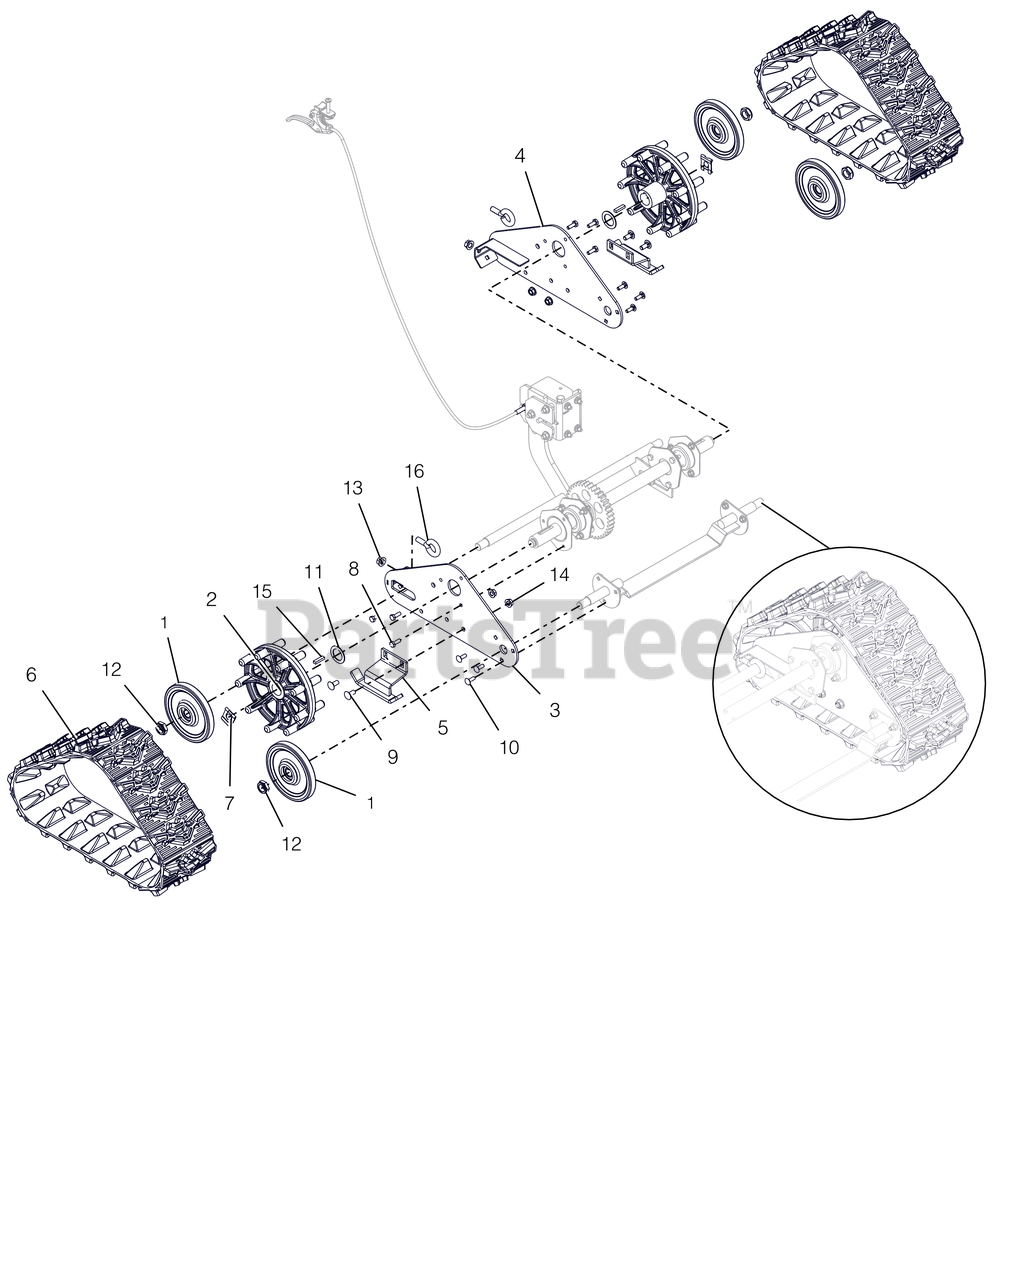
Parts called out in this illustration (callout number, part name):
1	WHEEL, BOGIE - SINGLE BEARING
2	WHEEL, MACHINED DRIVE
3	PLATE, SIDE-COMPACT RH WLDMT
4	PLATE, SIDE-COMPACT LH WLDMT
5	RUNNER, GUIDE-CMPT TRACK BLACK
6	TRACK, RUBBER COMPACT
7	CLIP, SNAP .625 DIA
8	@BLT-HEX .25-20X.75 GR5 YWZC
9	@BLT-RDHDSQNK .31-18X.75 G5YZ
10	@BLT-RDHDSQNK .25-20X.75 G5YZ
11	WSHR-FL-STL 1.010X1.505X.062YZ
12	@NUT-LK-NYL .625-18 YWZC
13	NUT-LK-CTR-FLG .38-16 YWZC
14	@NUT-LK-TOP-FLG .31-18 YWZC
15	KEY-RECT .25X.188X1.00
16	BLT-EYE .375-16X.880 YWZC
